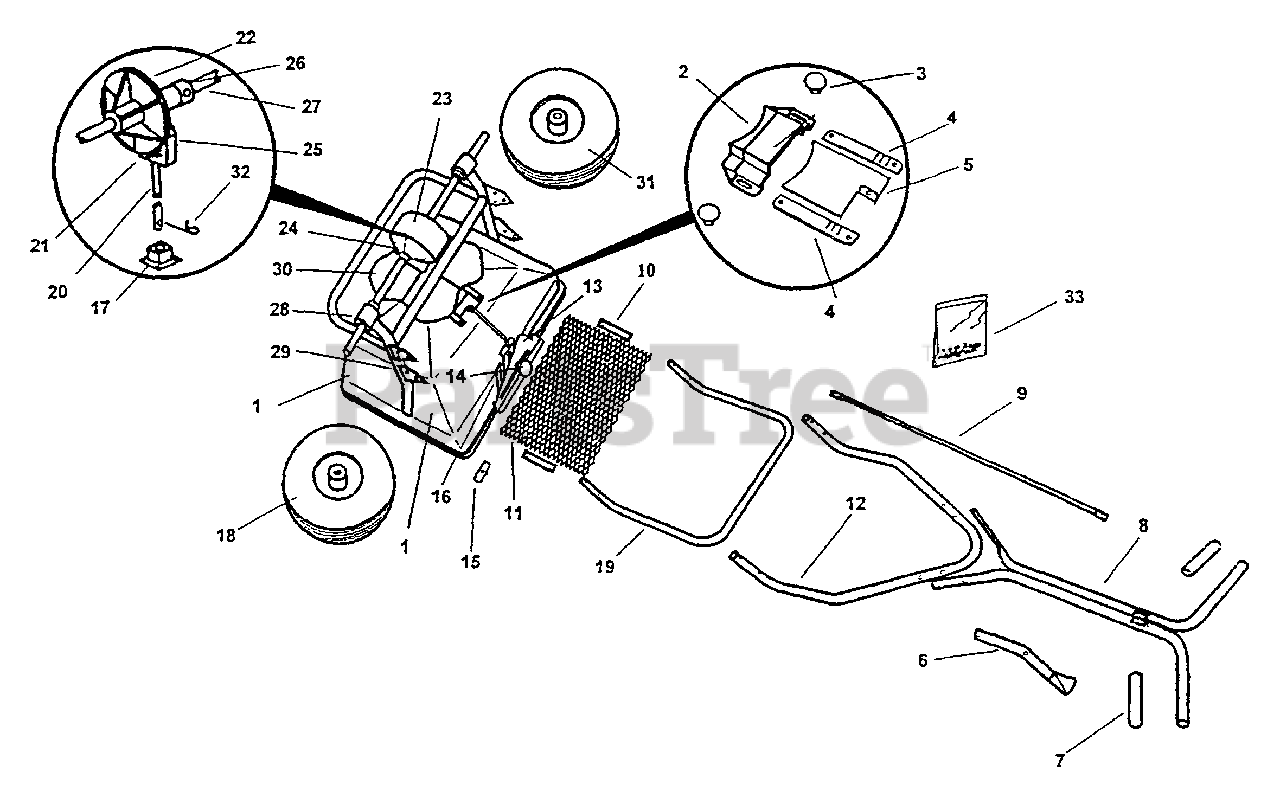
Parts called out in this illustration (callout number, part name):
1	HOPPER ASSY
1A	HOPPER
2	CHUTE, DISCHARGE
3	DISCHARGE CHUTE KNOB
4A	GUIDE, SHUTOFF PLATE - RIGHT
4B	GUIDE, SHUTOFF PLATE - LEFT
5	SHUTOFF PLATE
6	HANDLE LEVER ASSY W/ CHAIN
7	GRIP, HANDLE
8	UPPER HANDLE
9	TUBE, CONTROL
10	SCREEN CLIPS
11	SCREEN, HOPPER
12	BRACE, HANDLE
13	RATE PLATE
14	RATE CONTROL KNOB
15	POINTER
16	SPRING ASSY
17	IMPELLER SHAFT BEARING
18	DRIVE WHEEL
19	LEG
20	WASHER - 3/4"
21	GEAR, SHAFT
22	GEAR, AXLE
23	BOLT, 1/2×1 HEX HD
24	CLAMP, GEAR COVER
25	SUPPORT, GEAR
26	AXLE COLLAR W/ SET SCREW
27	AXLE
28	BEARING, AXLE
29	FRAME
30	IMPELLER
31	WHEEL, FREE
32	AGITATOR
33	WASHER - 5/8"
